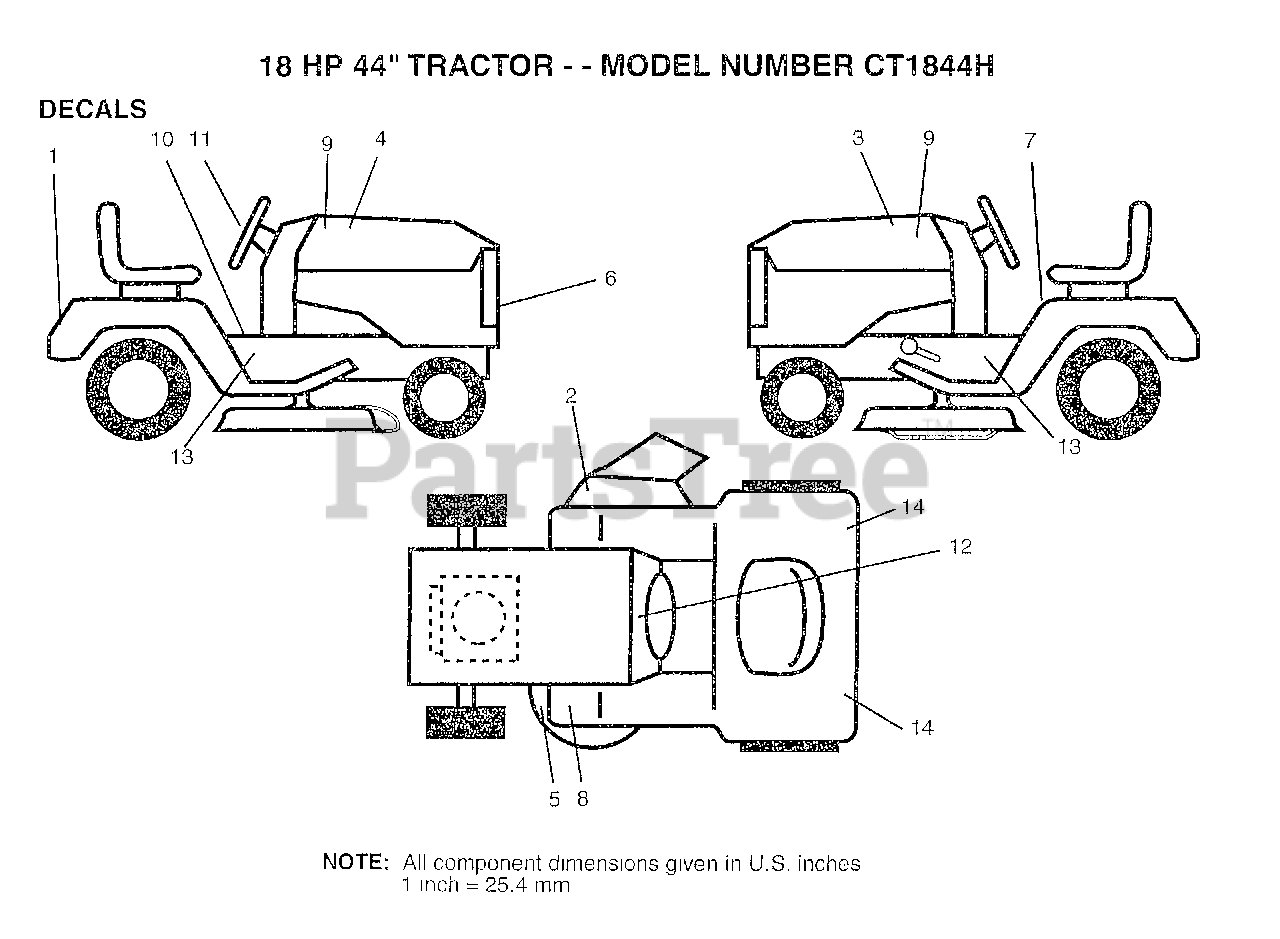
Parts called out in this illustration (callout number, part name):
1	DECAL.FENDER
2	"DECAL, WARNING"
3	DECAL.HOOD.LH.
4	DECAL.HOOD.RH.
5	"DECAL.V.BELT.44"""
6	DECAL.GRILLE
7	DECAL CAUTION
8	DECAL T
9	DECAL.HOOD.INSERT
10	DECAL BRAK PARK
11	DECAL INST STRWHL
12	DECAL.DASH.INSTR.
14	REFLECTOR-TAIL YT
